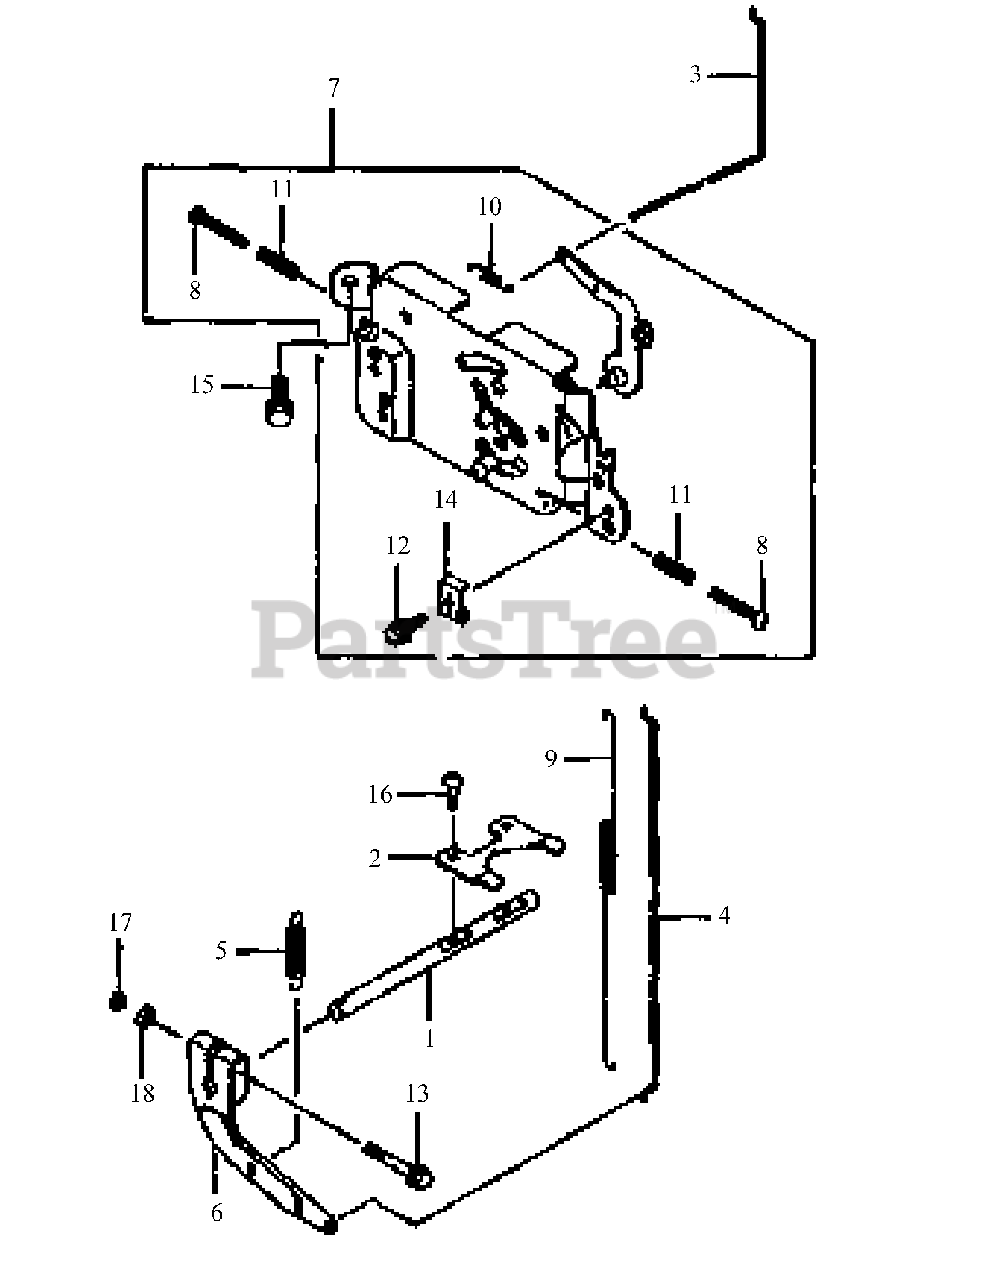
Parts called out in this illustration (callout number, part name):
5	Spring, Governor
6	Arm, Governor
7	Panel, Control
10	Spring
15	Bolt, Flange
18	Washer, Plain
